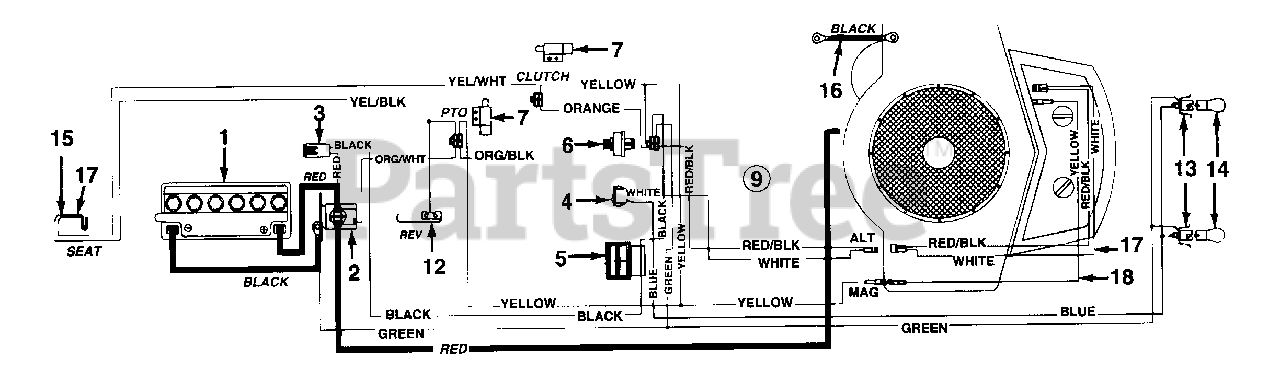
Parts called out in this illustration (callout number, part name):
1	Battery
2	Solenoid
3	Fuse 7.5 Amps
4	Light Switch
5	Ammeter
6	Ignition Switch
7	Safety Switch
9	Wire Harness
12	Safety Switch (Reverse)
13	Socket
14	Bulb (Headlight)
15	Safety Switch (Seat)
16	Ground Wire 7.5" Lg.
17	Safety Switch (Seat)
18	Harness Adapter
19	Harness Adapter
